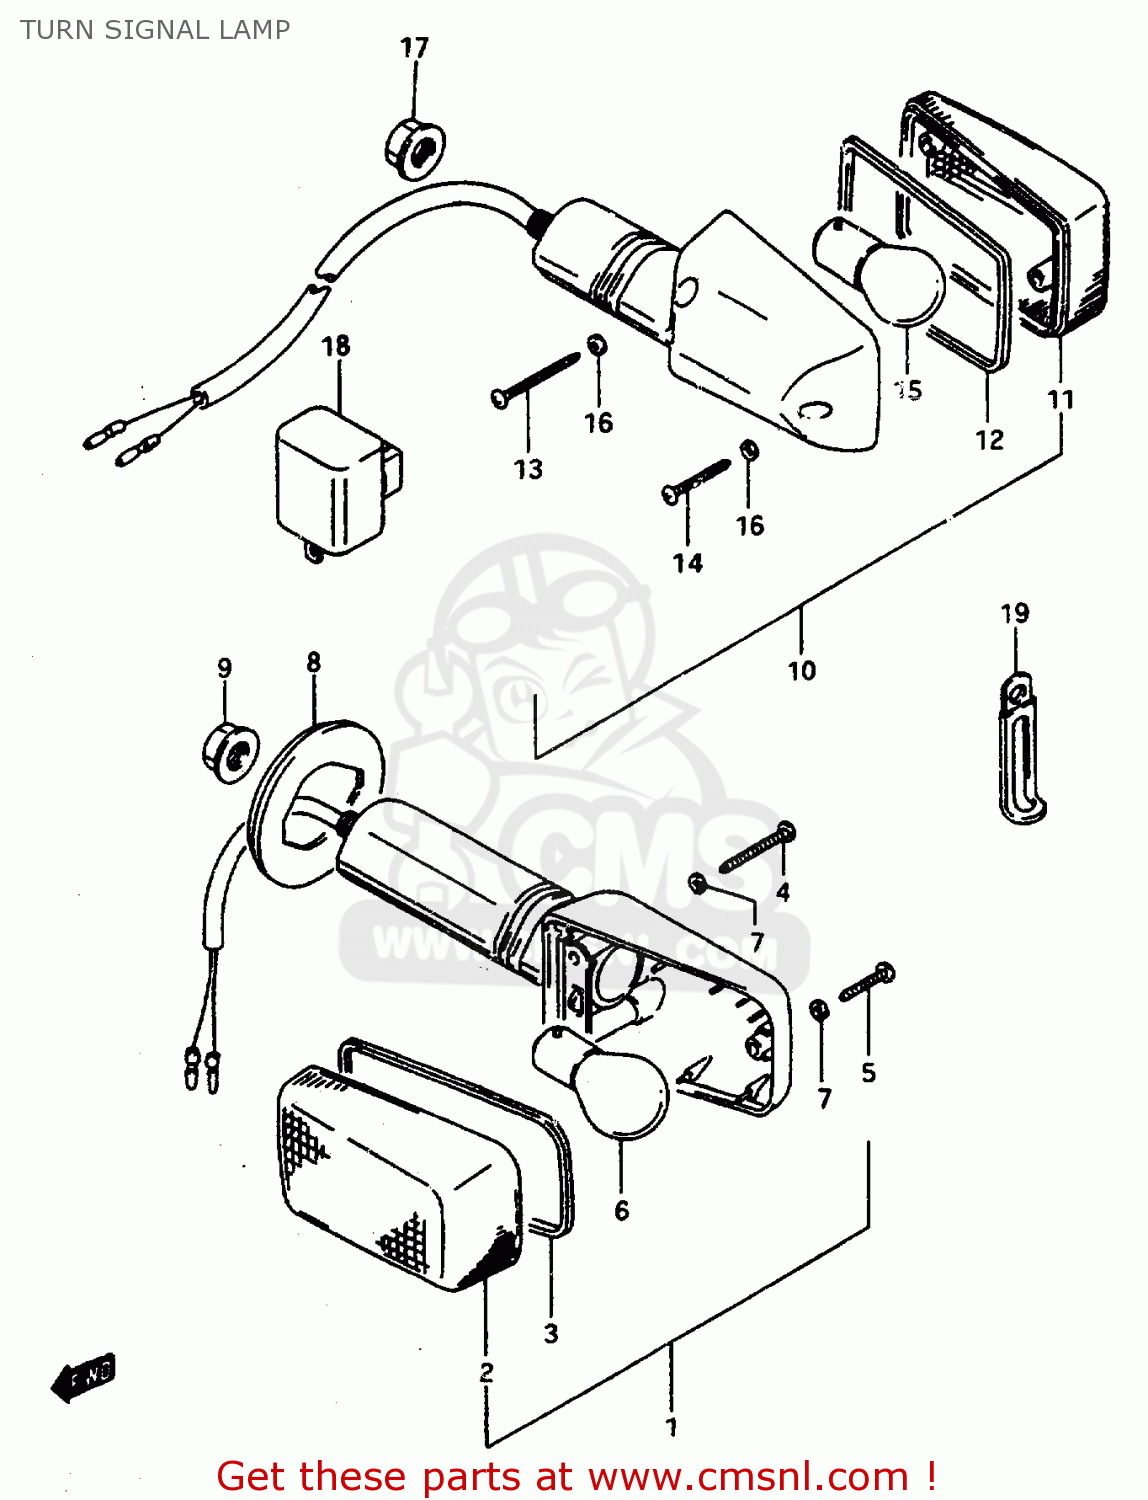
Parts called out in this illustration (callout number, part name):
1	LAMP ASSY,FR TURN SIGNAL
2	LENS
3	GASKET (NAS)
4	SCREW(3X30)
5	SCREW
6	BULB(12V21W)
7	GASKET (NAS)
8	GROMMET
9	NUT
10	LAMP ASSY,RR TURNSIGNAL
11	LENS
12	GASKET (NAS)
13	SCREW(3X30)
14	SCREW
15	BULB(12V21W)
16	GASKET (NAS)
17	NUT
18	RELAY ASSY,TURNSIGNAL LAMP
19	CLAMP(L:45)
